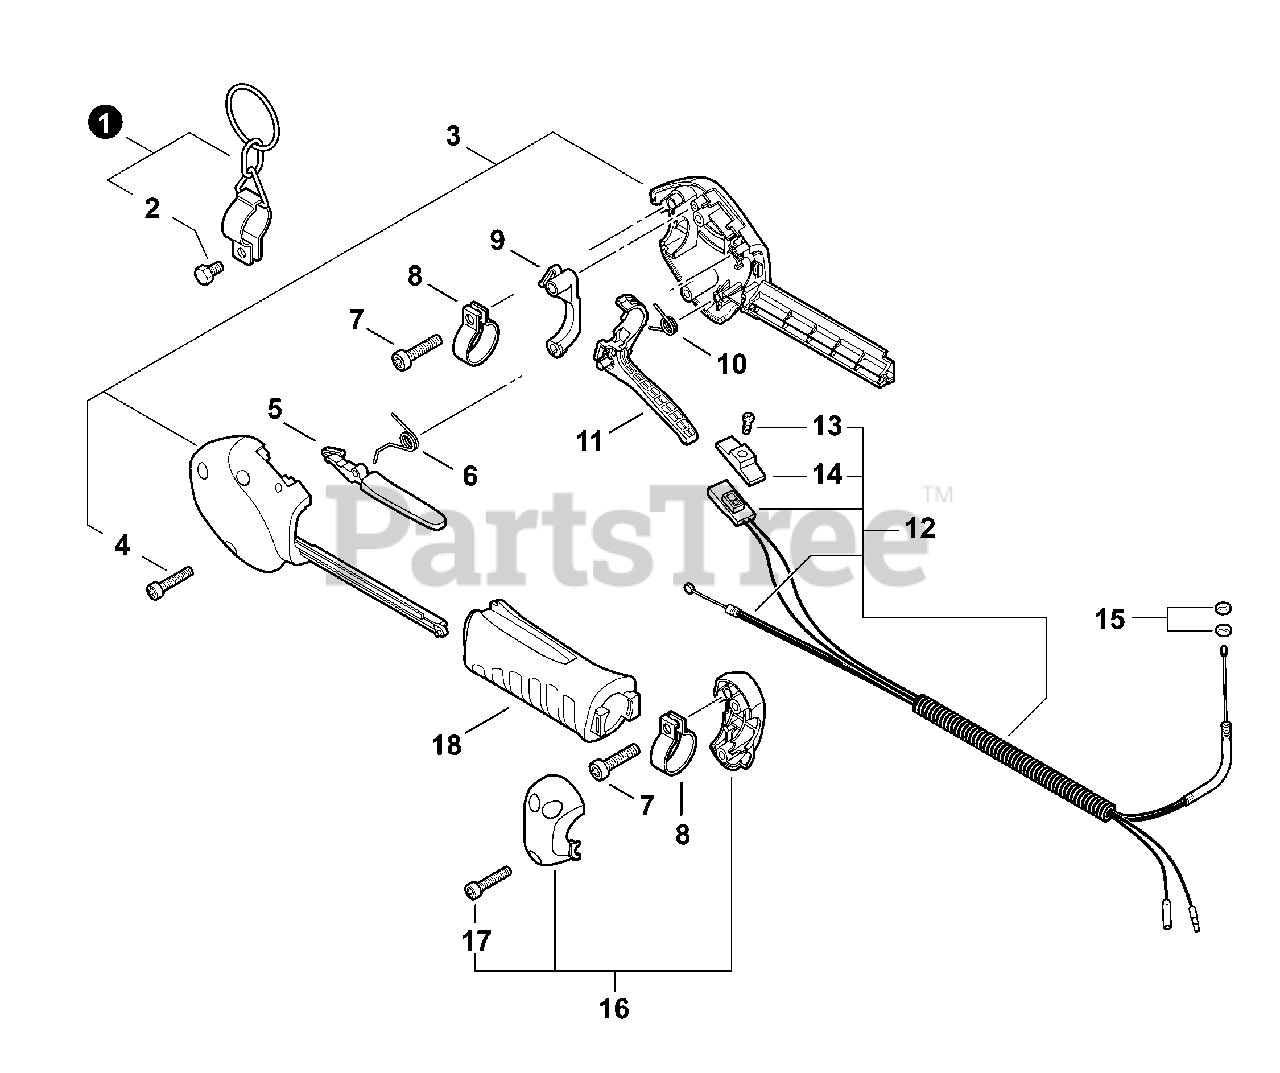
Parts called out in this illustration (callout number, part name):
1	HARNESS HANGER KIT
2	BOLT - 5X12
3	CONTROL HANDLE KIT
4	SCREW - 5X20
5	LEVER, THROTTLE LOCKOUT
6	SPRING, LEVER RETURN
7	SCREW - 5X20
9	LOCKOUT, TRIGGER
10	SPRING, TRIGGER
11	TRIGGER, THROTTLE
12	CONTROL CABLE ASSY
13	SCREW - 3X10
14	KNOB, SWITCH - ORANGE
16	HANDLE RETAINER KIT
17	SCREW - 5X20
18	GRIP, HANDLE
